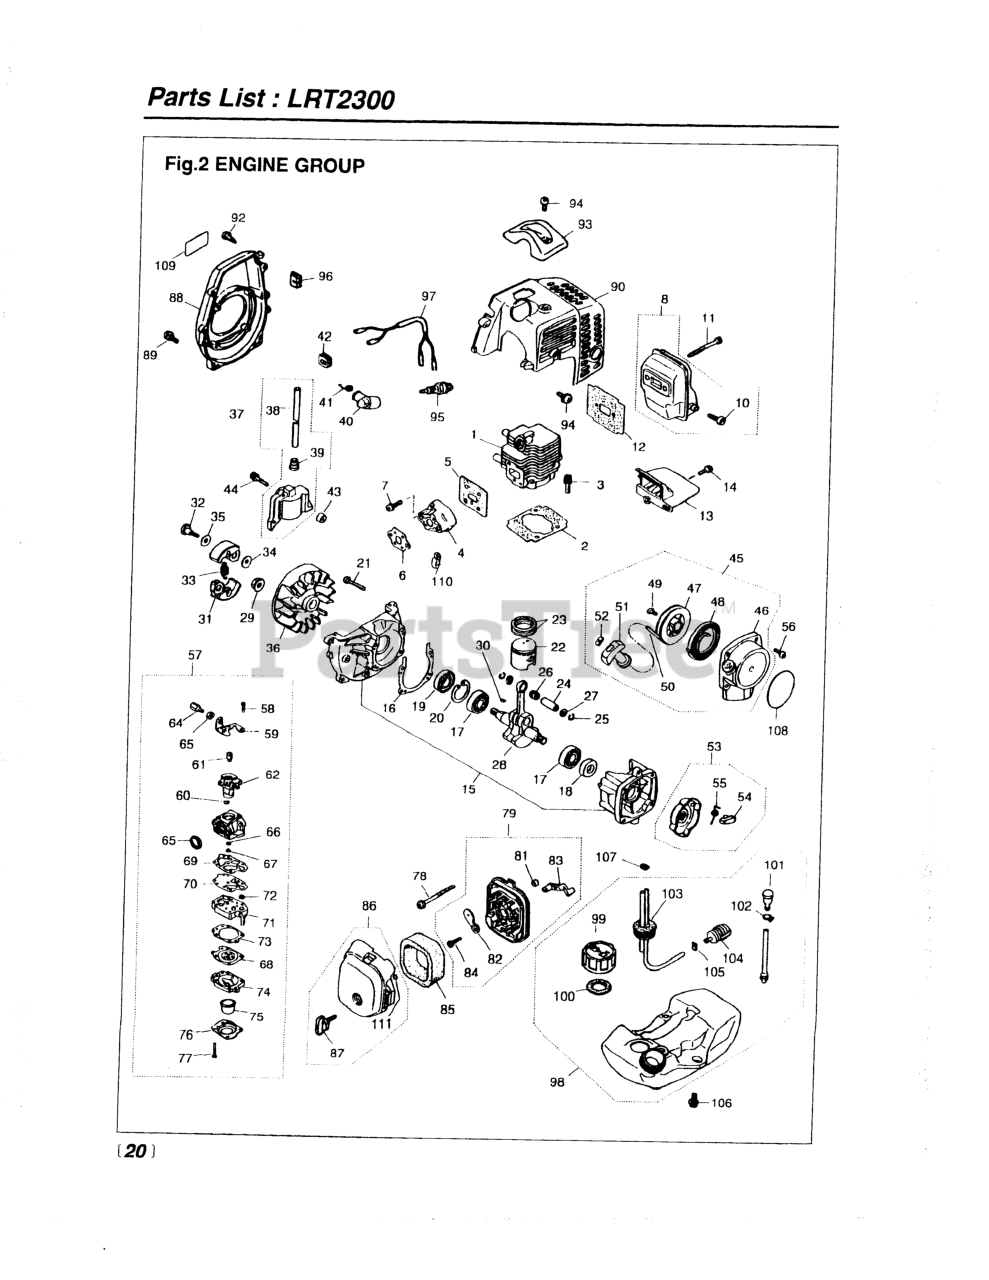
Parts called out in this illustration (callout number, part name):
1	CYLINDER
3	BOLT, M5 X 22
7	SCREW, M5X20 (RPLS.1400-75510)
8	MUFFLER ASSY (RPLS 5501- )
11	BOLT, M5 x 50
12	GASKET, MUFFLER
14	SCREW, M4 X 16
15	CRANKCASE
17	BEARING
18	SEAL, OIL (RPLS 1100-21210)
19	SEAL, OIL (RPLS 1140-21220)
20	RING, SNAP, M28 x 1.2
21	BOLT, M5 X 30
22	PISTON (REPLACES 1140-41110)
23	RING, PISTON (RPLS 1850-41210)
24	PIN, PISTON 5x8x26
25	RING, SNAP (RPLS 1101-41320)
27	WASHER
28	CRANKSHAFT (RPLS 1850-42000)
30	KEY
32	BOLT
33	SPRING, CLUTCH (RPLS-51220)
34	WASHER, FLAT (USE 182303)
37	COIL ASSY (RPLS 5500-71200)
38	CORD
39	CAP
41	SPRING
42	GROMMET
43	SPACER (RPLS -71260)
44	BOLT
45	RECOIL ASSEMBLY
46	CASE
47	REEL
48	SPRING, SPIRAL
49	SCREW (RPLS -75150)
51	KNOB
52	PLATE, STOPPER
53	PULLEY ASSY (RPLS -75210)
54	RATCHET (RPLS 1850-75220)
55	SPRING, RETURN
56	SCREW, M4 X 16
57	CARBURETOR
58	SCREW
60	RING
61	SWIVEL
62	VALVE ASSY
64	NUT, CABLE ADJUSTER
65	RING, PACKING
66	RING, O
67	JET
68	DIAPHRAGM (USE 4810-81260)
69	GASKET, PUMP
70	DIAPHRAGM
71	BODY, PUMP
73	GASKET, DIAPHRAGM
74	BODY, PURGE
75	PUMP, PRIMING
76	COVER, PUMP
77	SCREW
78	SCREW, M5 x 60
79	BODY-A (RPLS -82101)
81	SLEEVE
82	PLATE, CHOKE (RPLS-82130)
83	LEVER, CHOKE
84	SCREW (REPLACES 50030272)
85	ELEMENT
87	KNOB (RPLS -82220)
88	COVER, FAN (RPLS-31110)
89	SCREW, M5X20 (RPLS.1400-75510)
92	SCREW, HOUSING
93	GUARD, PLUG
94	SCREW,M5 X 14 (RPLS 1400-15510
97	CORD COMP (RPLS -73200)
99	CAP (RPLS -85200)
100	PACKING
102	CLIP
103	PIPE COMPLETE
104	FILTER (RPLS 1850-85300)
105	CLIP (REPLACES 2841-31280)
106	SCREW
107	CLIP
108	LABEL, RECOIL
110	CLAMP
111	RING
NI	SCREW, CABLE ADJUSTER
NI	SCREW, M5 x 12
